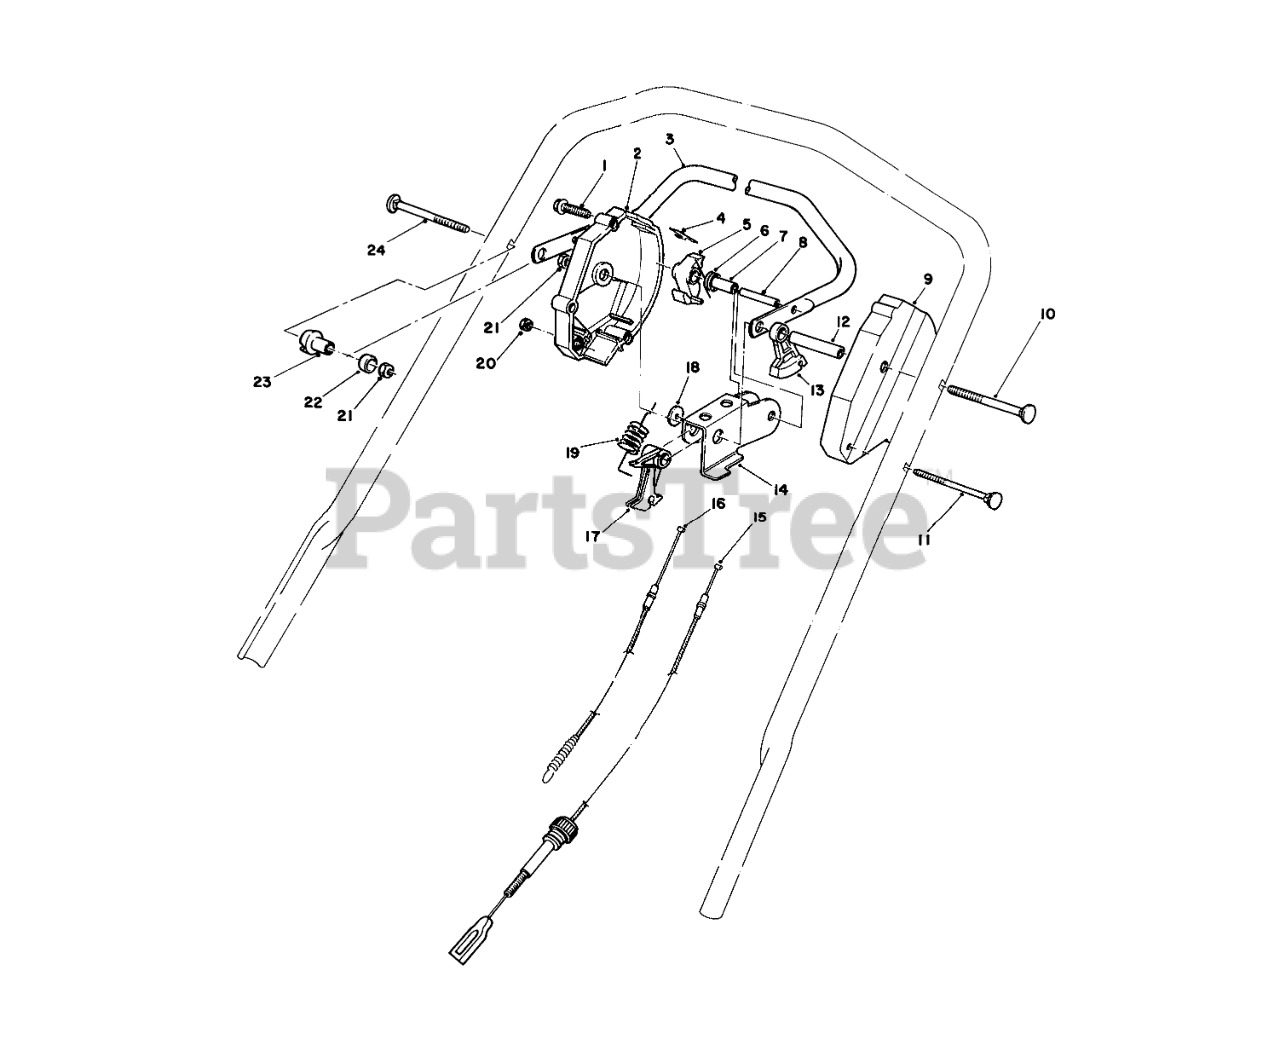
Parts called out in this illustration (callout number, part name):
1	SCREW-HWHTF
2	Housing Control R.H.
3	Bar-Control
4	SPRING-LEAF
5	HOOK-CONTROL
6	SPRING-TORSION
7	SPACER
8	PIN-ROLL, SLOTTED
9	HOUSING-CONTROL, LH
10	5/16-18 X 3 HNDLE SCREW
11	HANDLE SCREW
12	TUBING-SPACER
13	LEVER-TRACTION
14	Rocker
15	TRACTION CABLE
16	Cable-Clutch
17	LEVER-CABLE
18	PLASTIC WASHER
19	Spring-Detent
20	NUT-LOCK, NI
21	NUT-LOCK, NI
22	SPACER-NYLON
23	SPACER-SUPPORT
24	5/16-18 X 2 HNDLE SCREW
